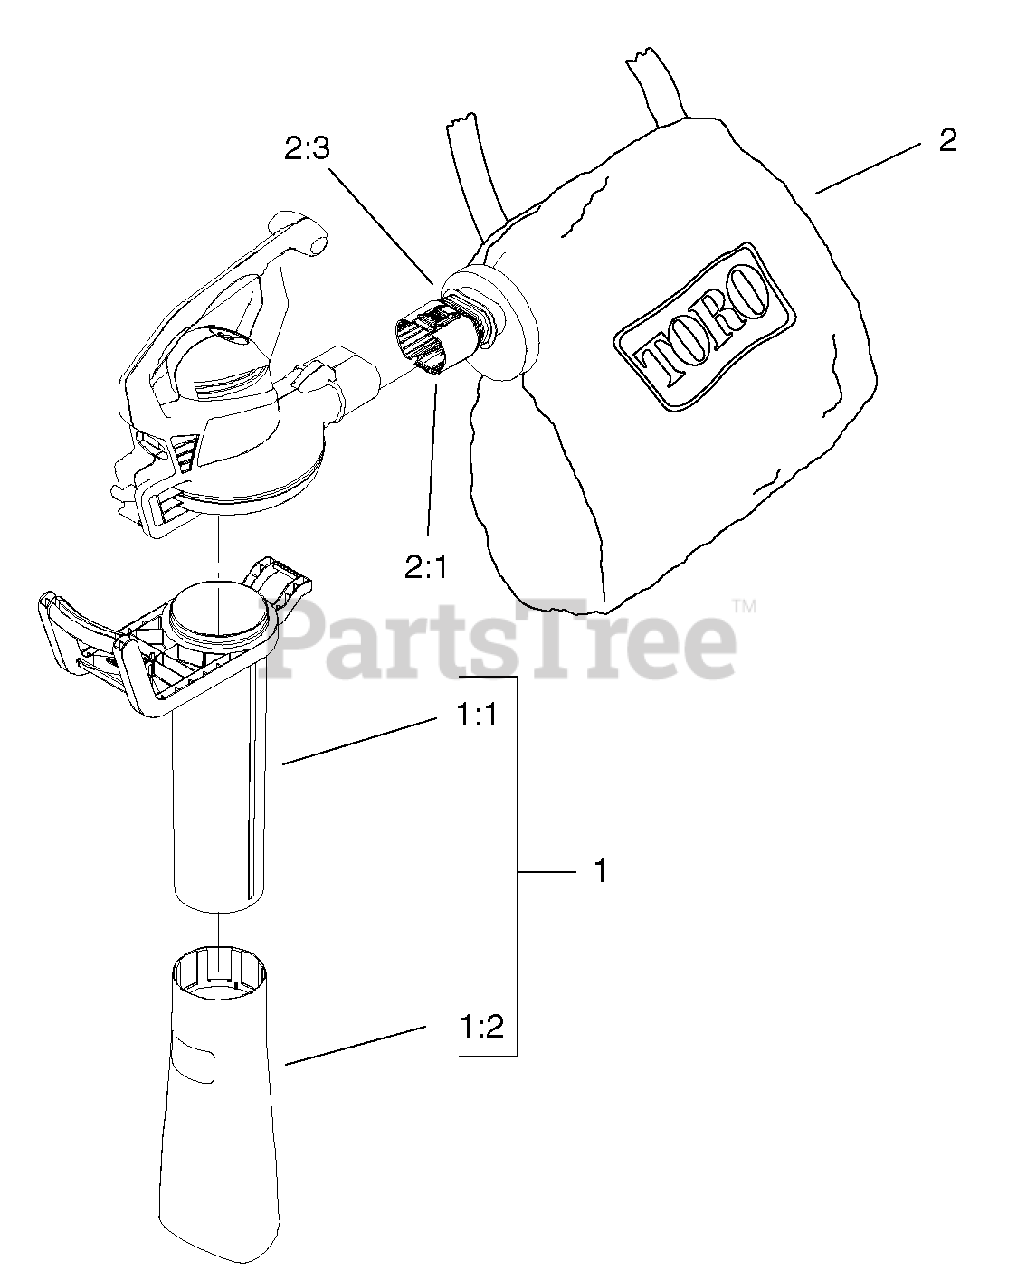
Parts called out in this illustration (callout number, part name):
1	Vac Tube ASM
1:1	TUBE-VAC, UPPER
1:2	TUBE-VAC, LOWER
2	BAG ASM
2:1	COLLAR-BAG
2:3	TIE-CABLE
